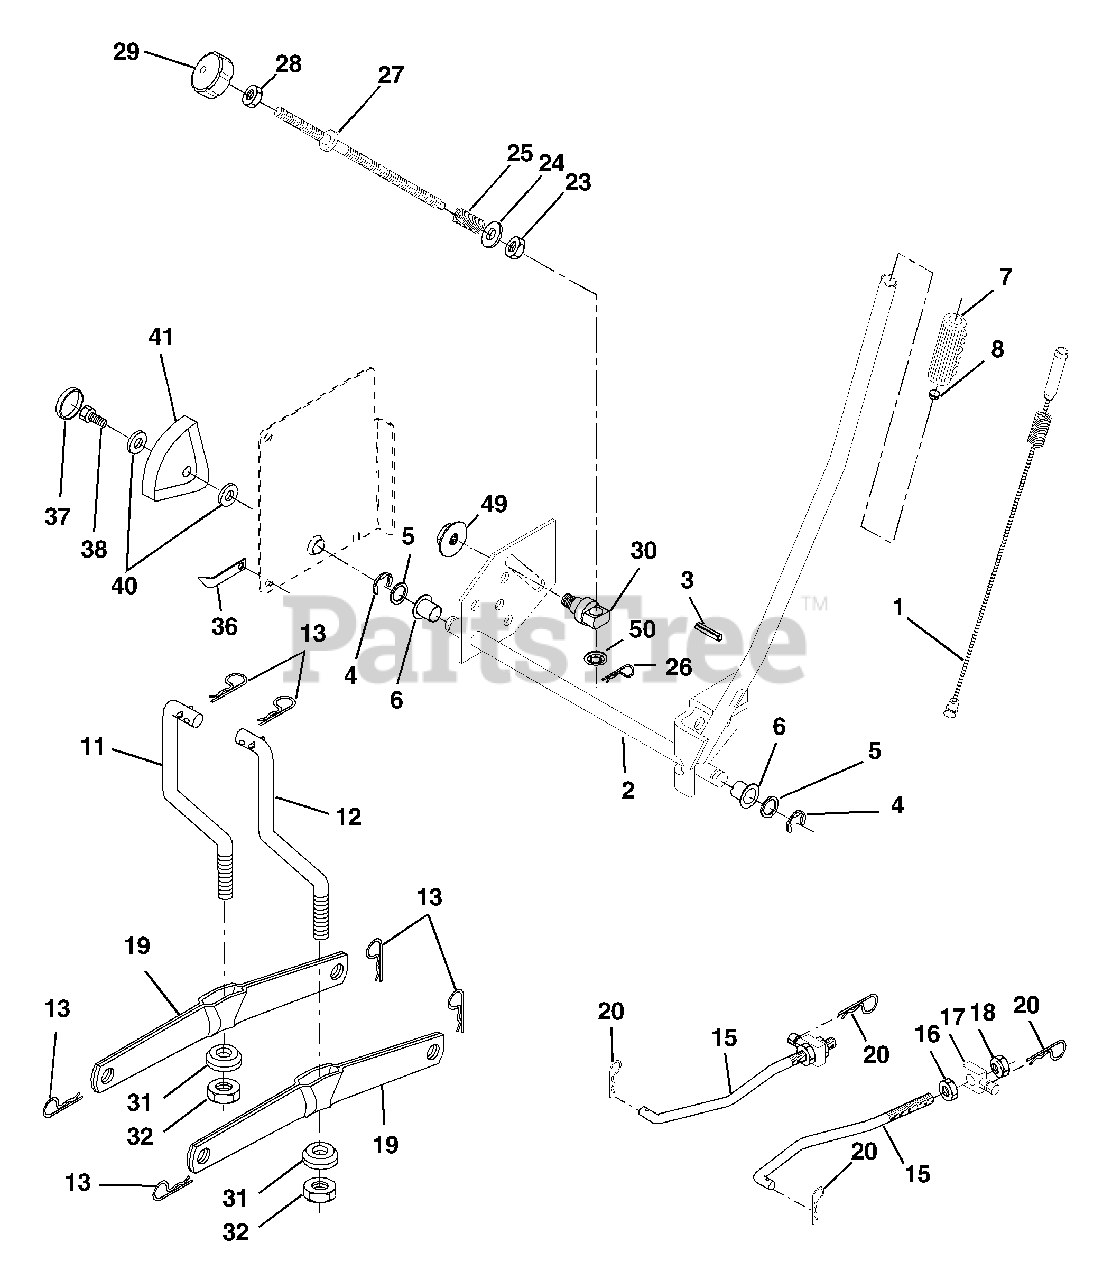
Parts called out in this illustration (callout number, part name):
1	Washer Asm Inner Spring W/Plunger
2	Shaft Asm. Lift
3	Pin Groove
4	E Ring #5133-62
5	Washer 21/32 x 1 x 21 Ga.
6	Bearing Nylon
7	Grip Handle
8	Button Plunger Black
11	Link Asm Lift L.H.
12	Link Asm Lift R.H.
13	Retainer Spring
15	Link Front
16	Nut Jam Hex 1/2-13 Unc
17	Trunnion Blk Zinc
18	Nut Lock W/Wsh 1/2-13 Unc
19	Arm Suspension Mower
20	Retainer Spring
23	Nut Special
24	Washer 13/32 x 5/8 x 16 Ga.
25	Spring 2-1/8
26	Retainer Clip
27	Rod Adj Lift Zinc
28	Nut Hex Jam 3/8-16 Unc
29	Knob Inf 3/8-16 unc
30	Trunnion Infin Height
31	Bearing, Pvt. Lift.
32	Nut Crownlock 3/8-24
36	Pointer Height Indicator
37	Plug Hole Blk
38	Screw 5/16-18 x 1
40	Washer 11/32 x 1-1/2 x 10 Ga
41	Scale Ind Height Blk
49	Nut Hex flange lock
50	Nut Push Phos & Oil
